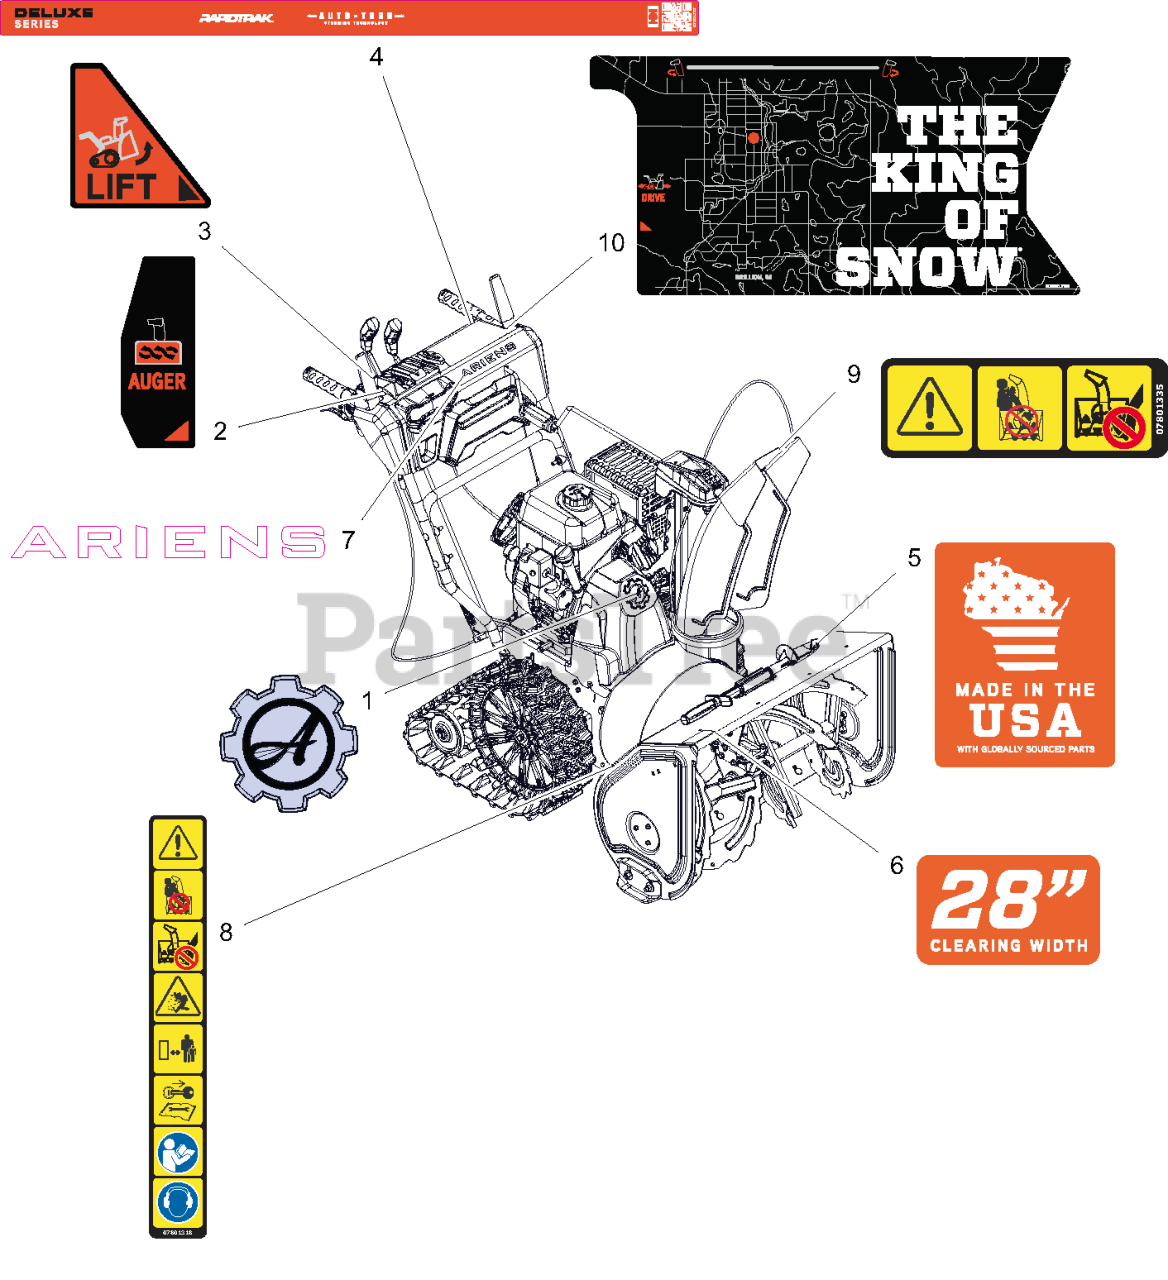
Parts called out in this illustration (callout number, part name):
1	DECAL- ARIENS GEAR BADGE
2	DECAL- CONTROL - AUGER
3	DECAL- CONTROL - TRACK LIFT
4	DECAL- DASH DLX RT
5	DECAL- MADE IN USA
6	DECAL- CLEARING - 28
7	DECAL- ARIENS - 7.46"
8	DECAL- SAFETY - DANGER
9	DECAL- DANGER
10	DECAL- CONTROL - LG RT ICEDRIL
